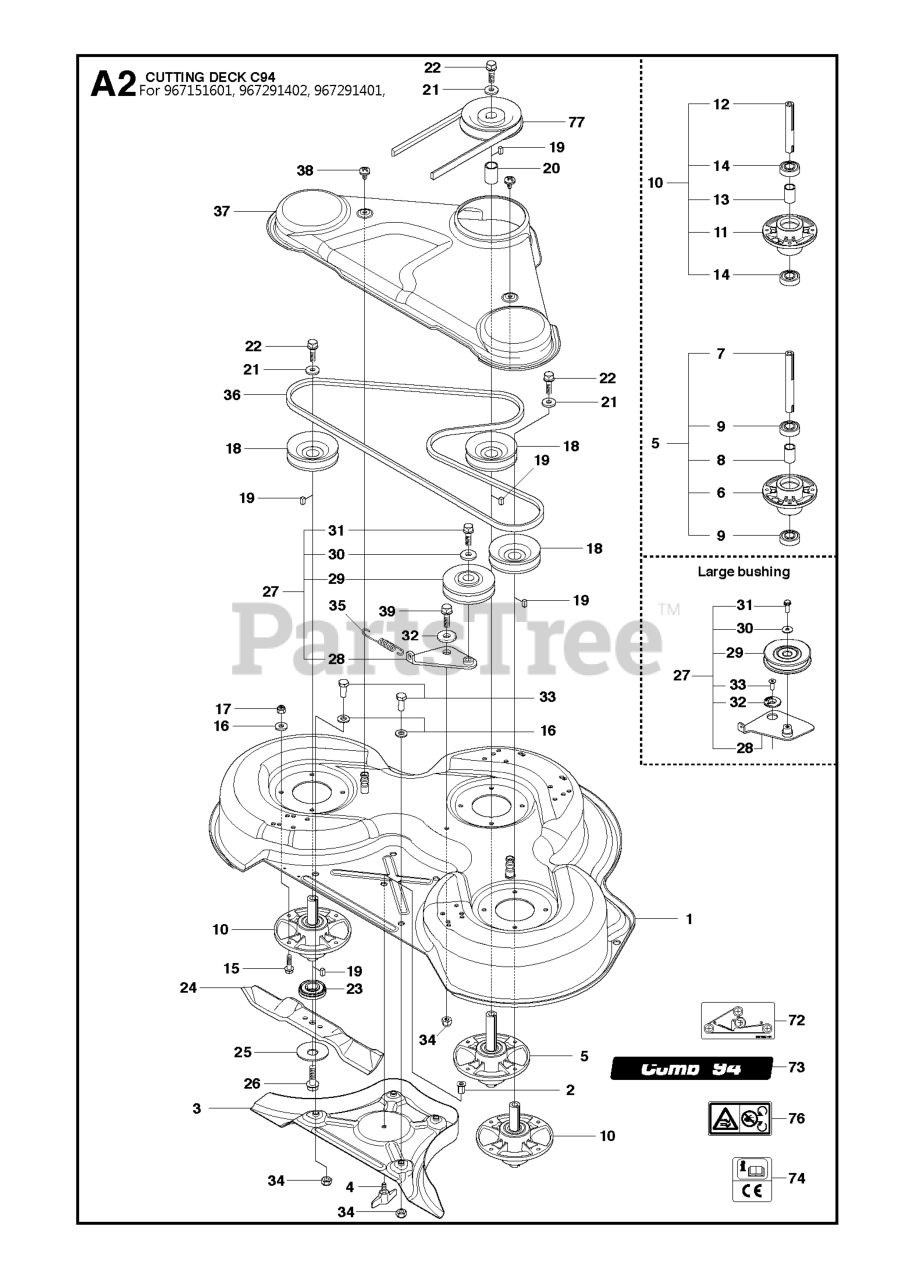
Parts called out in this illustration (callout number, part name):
1	CUTTING DECK CT94 GREY RIDER
3	PLUG C93 & C94
5	BLADE HOUSING ASSY
6	BEARING HOUSING
8	SPACING SLEEVE
10	BLADE HOUSING ASSY
11	BEARING HOUSING
13	SPACING SLEEVE
16	WASHER BRB 8.4X17
17	LOCKNUT M8
25	WASHER
27	BELT TENSIONER ASSY
27	BELT TENSIONER ASSY KIT
28	BELT TENSIONING ARM
29	PULLEY
30	SPACER
31	BOLT
32	WASHER
32	WASHER SHOULDER ASSY
34	LOCKNUT M8
37	BELT COVER C93 & C94 GREY
39	SCREW
